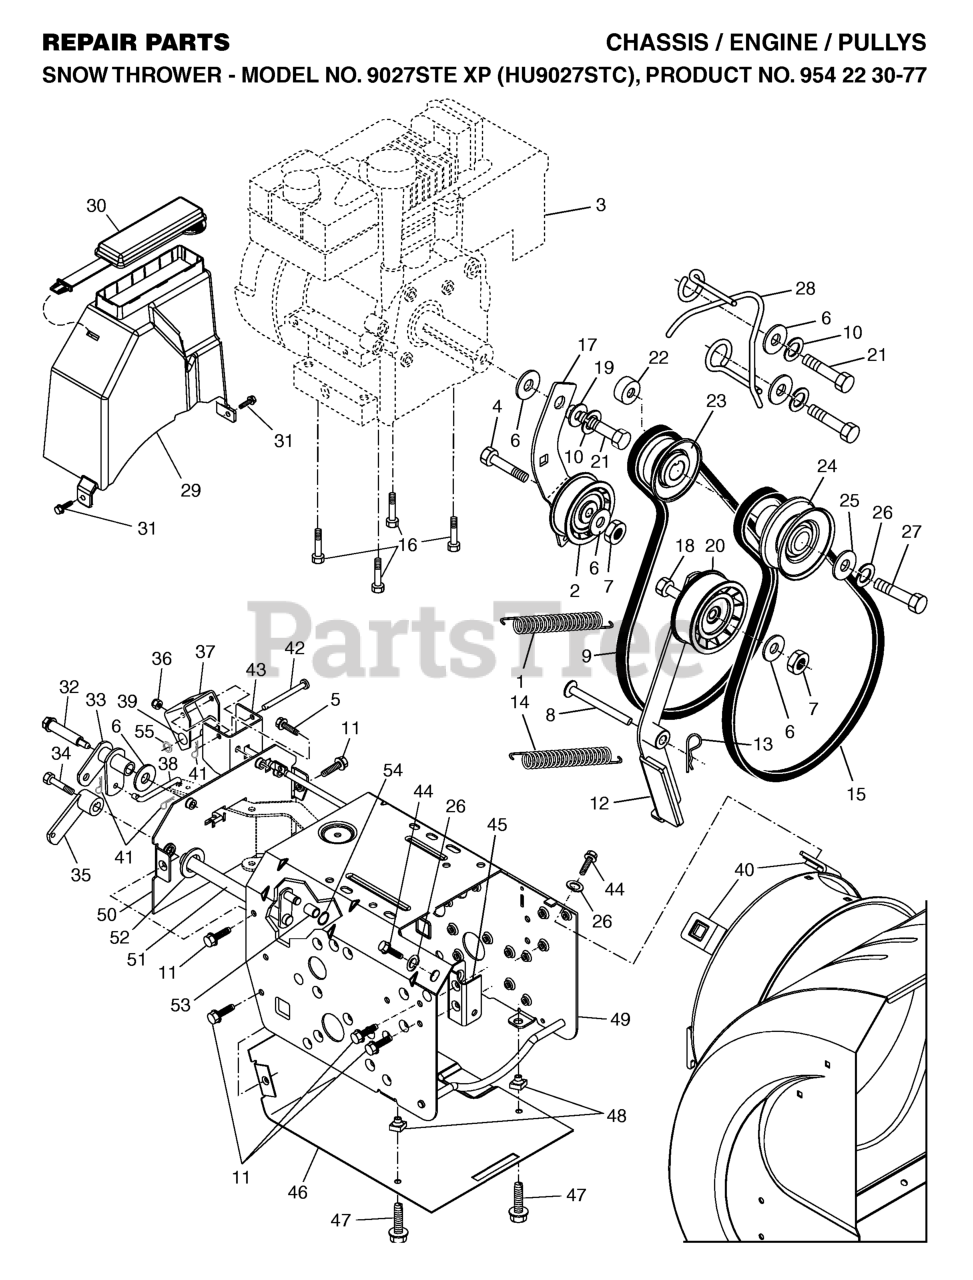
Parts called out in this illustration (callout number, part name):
1	RP SPRING, TRACTION IDLER
2	PULLEY.W/SPACER.2.25
4	BOLT.5/16-18X1-1/4 FULL.THREAD
5	SELF-TAPPING SCREW 5/16-18X3/4
6	STEEL WASHER
7	NUT.CENTERLOCK.5/16-
8	PIN, IDLER PIVOT
9	V-BELT, TRACTION DRIVE
10	WASHER.LOCK.HVY.HLCL.SPR.5/16
11	Screw 5/16-18 x 1/2 Hex, Self Tapping 5/16-18 x 1/2
12	ARM ASSEMBLY, IMPELLER IDLER
13	RETAINER CLIP PM
14	SPRING, BRAKE
15	V-BELT, IMPELLER DRIVE
16	BOLT, ENGINE, 3/8-16
17	IDLER ARM
18	HEX BOLT
19	RP BUSHING, IDLER PIVOT
20	PULLEY.W/SPACER.2.75
22	SPACER, ENGINE PULLEY
23	PULLEY,ENGINE TRACTION DRIVE
24	PULLEY, ENGINE IMPELLER DRIVE
26	LOCKWASHER
27	SCREW, HEX HD 3/8-24 X 1-3/8
28	GUIDE, BELT
29	COVER.ASM.BELT/STORAGE
30	COVER.STORAGE.SNOW
31	SCREW
32	BOLT, SHOULDER 5/16-18
33	BELLCRANK SHIFTER
35	ARM, AUGER CONTROL
36	NUT.71038.31-18.HEX.NYLOCK
37	BRACKET, PIVOT
38	LINK, SPEED CONTROL
39	TRUNNION, TRACTION
40	NUT, CAGE 3/8-16
41	RETAINER CLIP
42	PIN, PIVOT BRACKET
44	BOLT
45	BRACKET, IDLER PIVOT
46	PAN, FRAME BOTTOM
47	Screw, Hex Head 5/16-18 x 3/4
48	NUT.SPEED.5/16-18
49	FRAME ASSY
50	PLATE, FRAME END
51	CONTROL SHAFT WELDMENT
52	THRUST WASHER
53	ROLLER, ACTUATOR
54	RING.CRESENT
55	RETAINING RING LT
